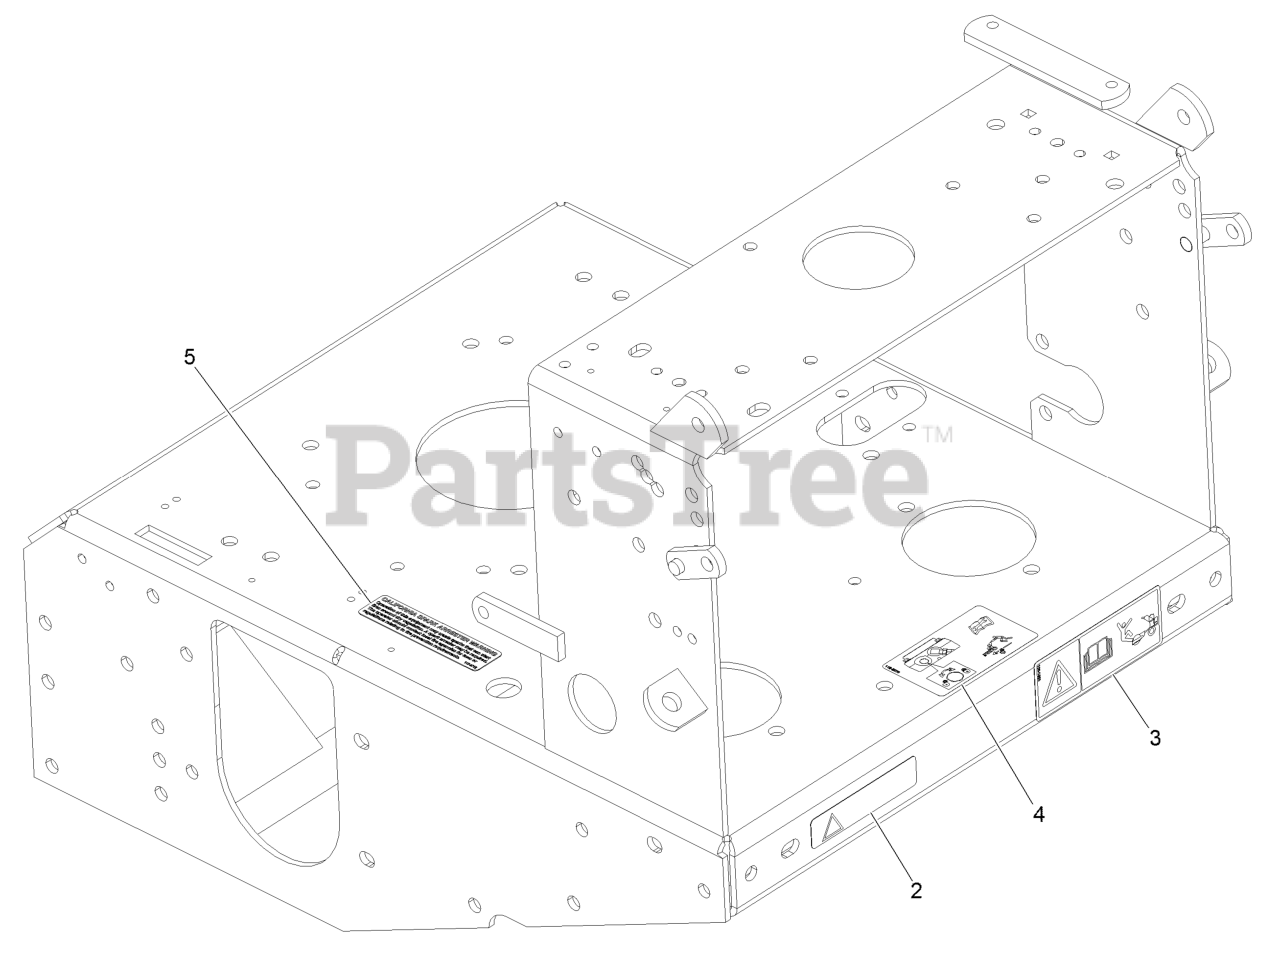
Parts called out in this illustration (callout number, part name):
2	DECAL-WARNING
3	DECAL-WARNING, SULKY
4	DECAL-DRIVE RELEASE
5	DECAL-ARRESTER, SPARK
